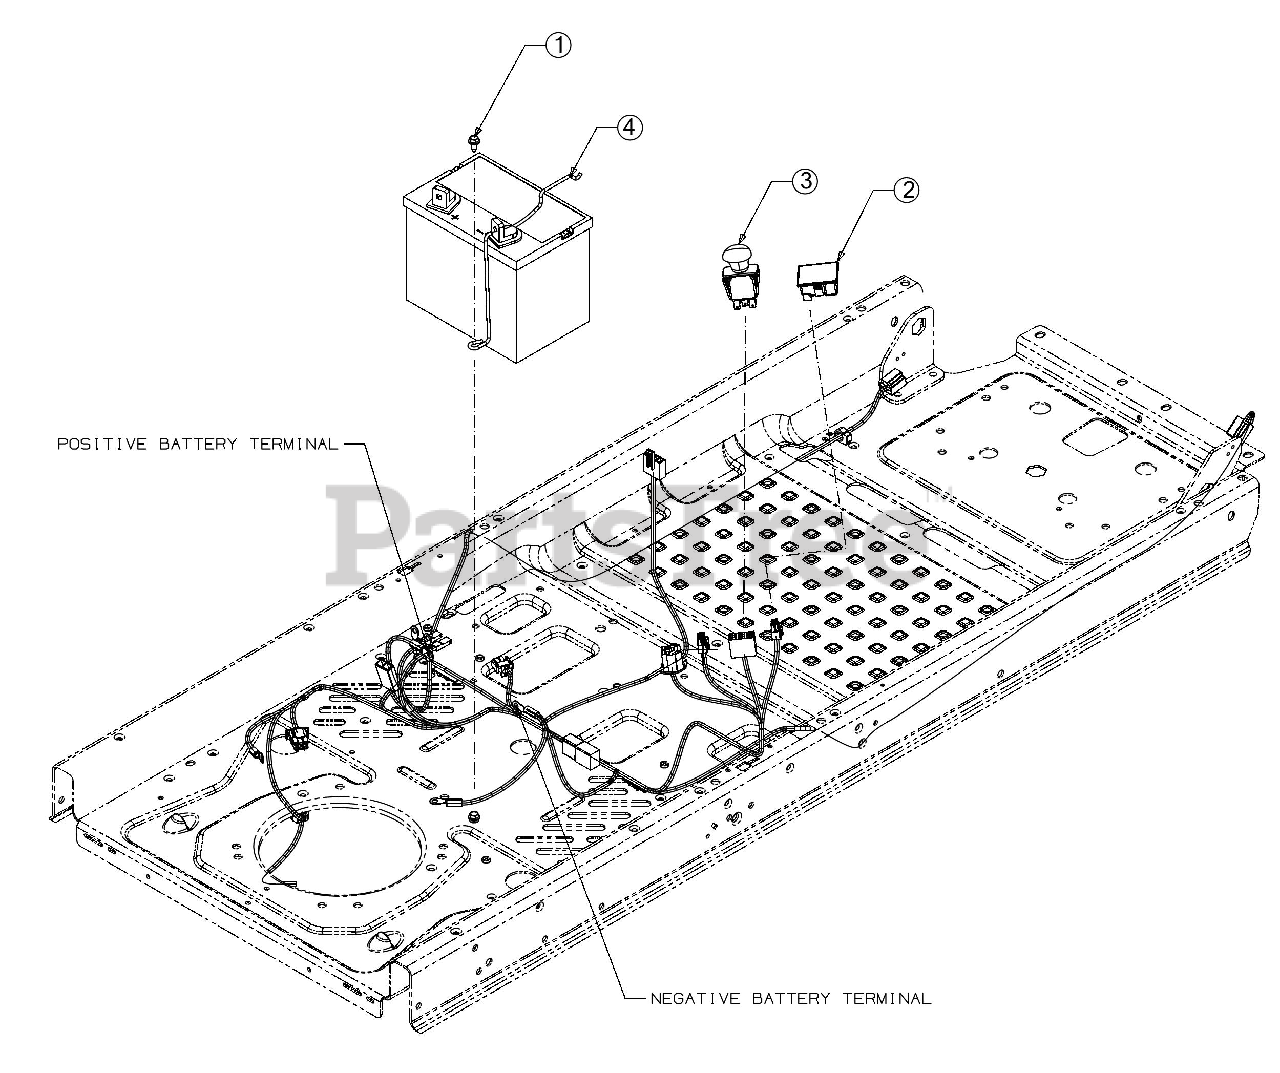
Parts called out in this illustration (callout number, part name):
1	SCREW 1/4-20X.625
3	PTO SWITCH
4	BATTERY RETAINER
